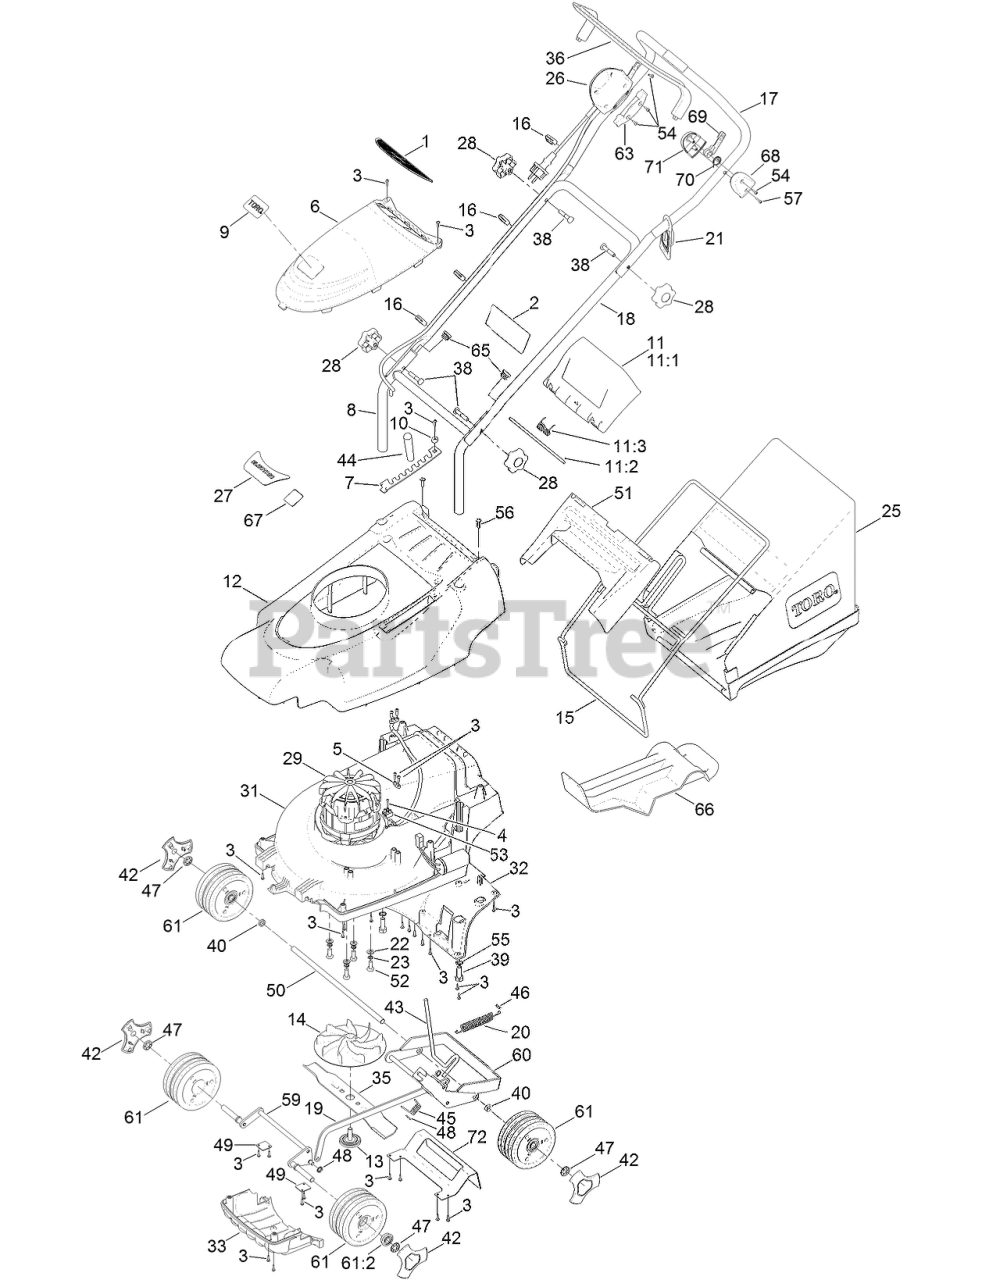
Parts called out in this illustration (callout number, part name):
1	MOULDING-VENT, SUPPORT
2	DECAL-SAFETY, ELECTRIC
5	CLAMP-CABLE
6	COVER-MOTOR
7	PLATE-HOC
8	HANDLEBAR-LOWER
9	DECAL-TORO
10	COVER-SCREW, HOC
11	FLAP-REAR ASM
11:1	DEFLECTOR-REAR
11:2	ROD-DEFLECTOR
11:3	SPRING-DEFLECTOR
12	COVER-TOP
13	BOLT-FIXING, CUTTERBAR
14	CARRIER-CUTTERBAR
15	FRAME-GRASSBAG
16	CLIP-CABLE
17	HANDLEBAR-UPPER
18	HANDLEBAR-MIDDLE
19	ROD-CONNECTING
20	SPRING-BALANCE, COUNTER
21	CLEAT-CABLE
22	WASHER
23	WASHER-SPRING
25	GRASSBAG
26	SWITCH AND LEAD ASM
28	KNOB-HANDLEBAR
31	UNDERDECK
32	THROWPLATE
35	CUTTERBAR
36	ARM-BAIL
38	BOLT-HANDLEBAR
39	SCREW-HH
40	SPACER-WHEEL, REAR
42	CAP-HUB
43	LEVER-HOC
44	KNOB-HOC
45	SPRING-HOC
46	PIN-SPRING, HOC
47	WASHER-STARLOCK
48	WASHER-STARLOCK
49	PLATE-PIVOT, AXLE
50	ROD-AXLE, REAR
51	TOP-GRASSBAG
52	BOLT-MOTOR
53	BLOCK-TERMINAL
55	WASHER
56	SCREW
57	SCREW-PPH
59	FRONT AXLE ASM
60	REAR AXLE ASM
61	WHEEL ASM
61:2	BEARING-WHEEL
63	SWITCH-LEFT, LOWER
65	PLUG-TUBE
66	PLUG-MULCHING
67	DECAL-HOC
68	MOUNT-LEFT
69	LEVER-MOUNT
70	SPRING-BAILARM
71	MOUNT-RIGHT
72	GUARD-PLATE, AXLE
